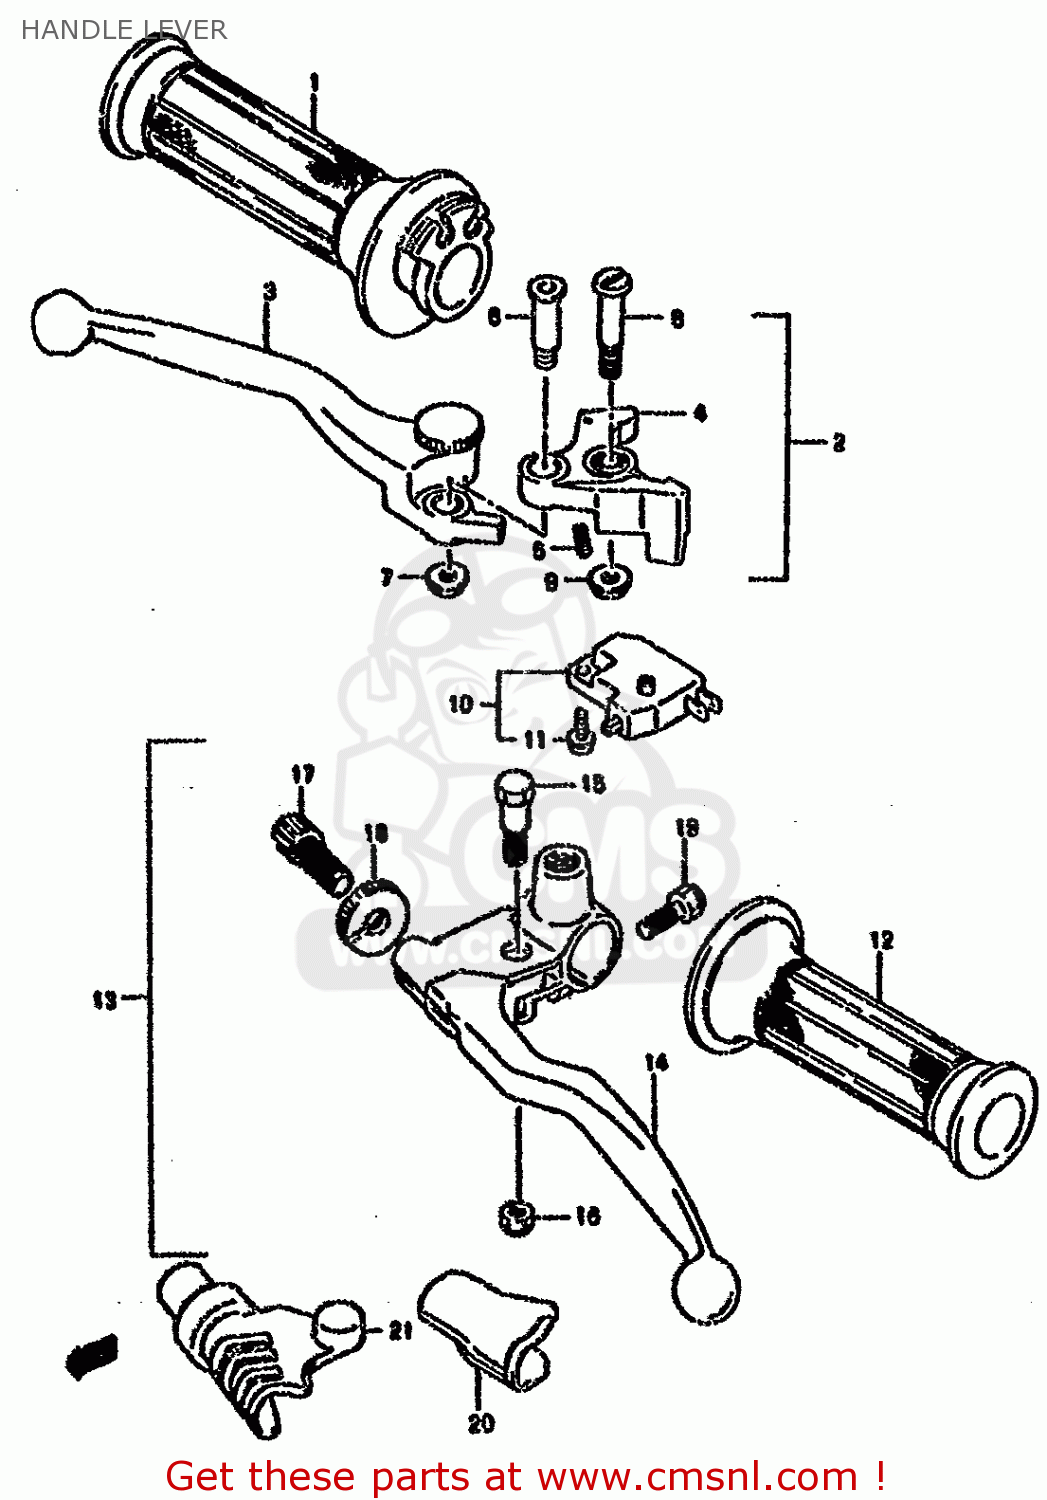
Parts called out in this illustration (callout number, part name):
1	GRIP,THROTTLE
2	LEVER ASSEMBLY,BRAKE
3	LEVER,ADJUST
4	KNOCKER
5	SPRING
6	BOLT,LEVER
7	NUT
8	BOLT,LEVER PIVOT
9	NUT 6MM
10	SWITCH ASSEMBLY,STOP
11	SCREW
12	GRIP,L
13	LEVER,CLUTCH
14	LEVER,CLUTCH
15	BOLT,LEVER SET
16	NUT
17	ADJUSTER,WIRE
18	NUT,LOCK
19	BOLT 6X20
20	COVER,CLUTCH LEVER
21	COVER,CLUTCH LEVER
